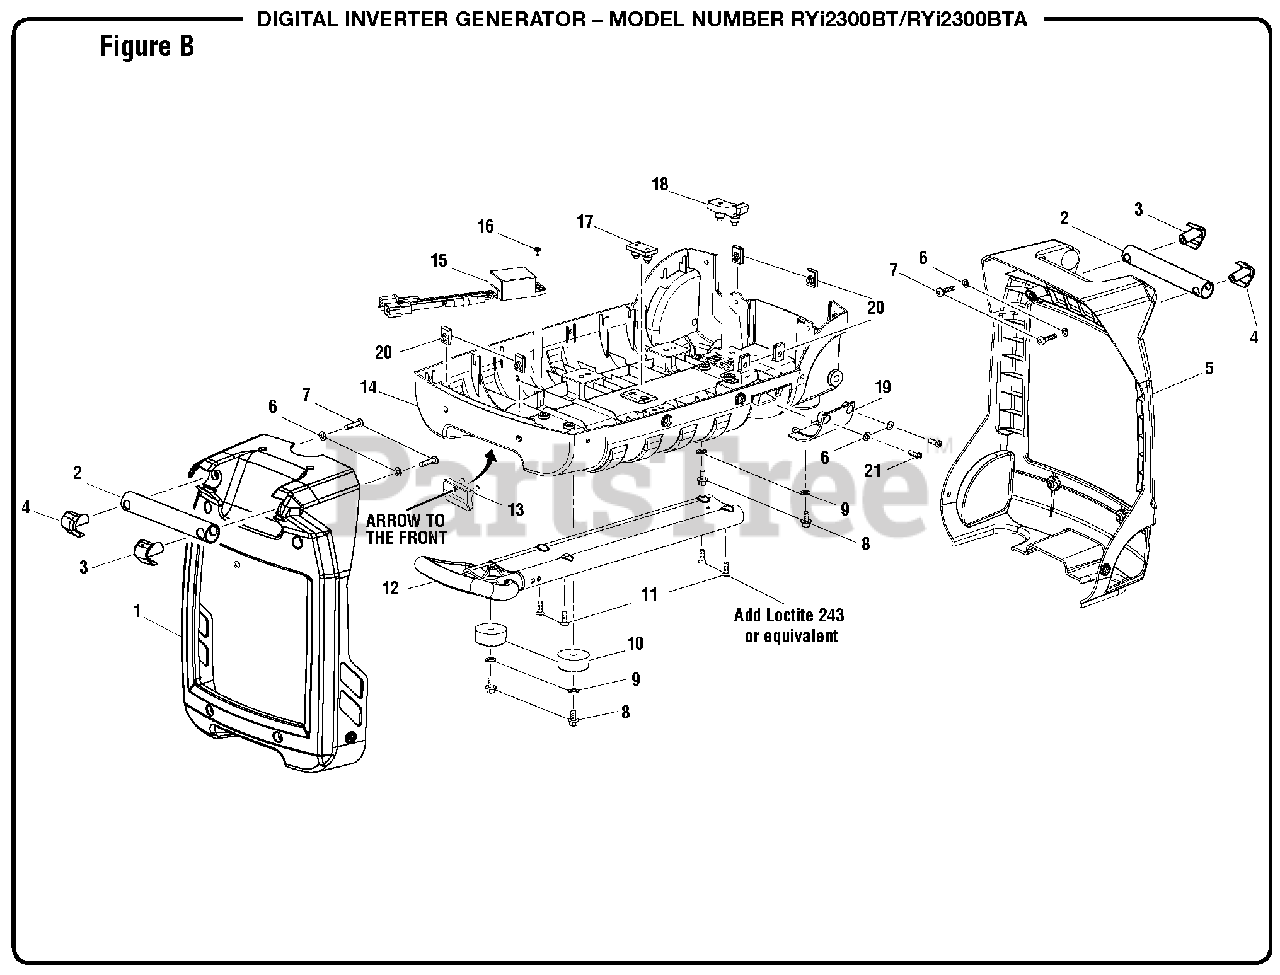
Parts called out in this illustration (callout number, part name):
1	Front Cover
2	Handle Tube
3	Handle Cap (Right)
4	Handle Cap (Left)
5	Back Cover
6	Washer (M5.3)
7	Screw (M5 x 20 mm, Button Soc. Hd.)
8	Bolt (M6 x 12 mm, Hex Hd.)
9	Lock Washer
10	Isolator Foot
11	Screw (M5 x 16 mm, Flat Hd.)
12	Handle Assembly
13	Handle Bumper
14	Bottom Base
15	Regulator (AC to DC)
16	Flange Washer
17	Engine Support Isolator (Front)
18	Engine Support Isolator (Back)
19	Oil Drain Door
20	U-Clip (M5)
21	Screw (M5 x 12 mm, Phillips Hd.)
